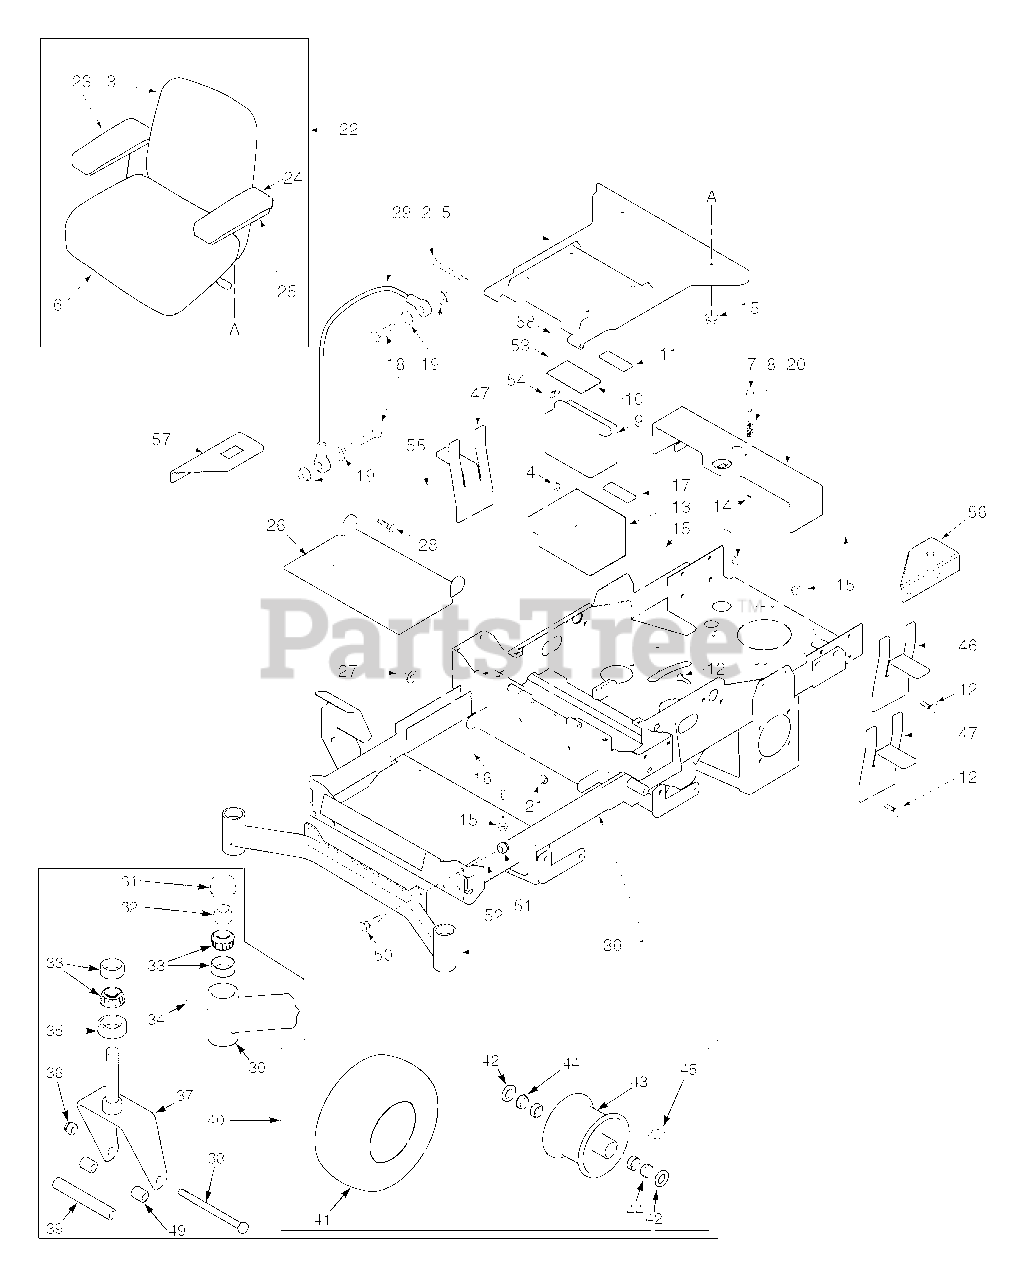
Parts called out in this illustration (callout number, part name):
1	Main Frame Assembly w/decals
2	Bolt, Hex Head 5/16-18 x 3-3/4"
3	Cushion, Back
4	Nut, Serr. Flange 3/8-16
5	Plate, Seat Mounting
6	Cushion, Lower Seat
7	Pin Retainer, Spring
8	Spring
9	Battery
10	Battery Cover
11	Battery Hold Down Pad
12	Bolt, Carr. 5/16-18 x 3/4"
13	Battery Box
14	Roll Pin, Spring 5/32 x 3/4"
15	Nut, Serr. Flange 5/16-18
16	Bolt, Hex Head 3/8-16 x 1"
17	Pad, Rubber
18	Bolt, Hex Head 1/4-20 x 1-1/4"
19	Nut, Serr. Flange 1/4-20
20	Seat Base Support
21	Nut, Elastic Stop 5/16-18
22	Seat Assembly w/ adj. rails
23	Arm Pad, RH
24	Arm Pad, LH
25	Channel, Armrest
26	Footplate
27	Nut, Elastic Stop 3/8-16
28	Bolt, Hex Head 3/8-16 x 1"
29	Cable, Seat Stop
30	Weldment, Caster Support
31	Cap, Grease
32	Nut, Elastic Stop 1.0-14
33	Bearing Set
34	Plug, 1/4-28
35	Seal, 2.0" OD x 1.625" ID
36	Nut, Elastic Stop 1/2-13
37	Yoke, Front Caster Wheel
38	Bolt, Hex Head 1/2-13 x 7-1/2"
39	Sleeve
40	Caster Wheel Assembly
41	Tire, 13 x 5.0-6 Smooth
43	Rim
44	Roller Bearing
45	Fitting, Grease
46	Mounting Bracket, Oil Tank
47	Mounting Bracket, Fuel Tank
48	Seat Pan
49	Spacer, Caster Wheel
50	Bolt, Hex Head 7/16-14 x 1-1/4"
51	Nut, Elastic Stop 7/16-14
52	Lockwasher, 7/16
53	Lock Washer. 3/8 Spring
54	U-Nut, 3/8-16
55	Bolt, Carriage 5/16-18 x 1"
56	Bracket, Fuel Valve
57	Bracket, Hour Meter
58	Bolt, Hex Head 3/8-16 x 1-1/4"
